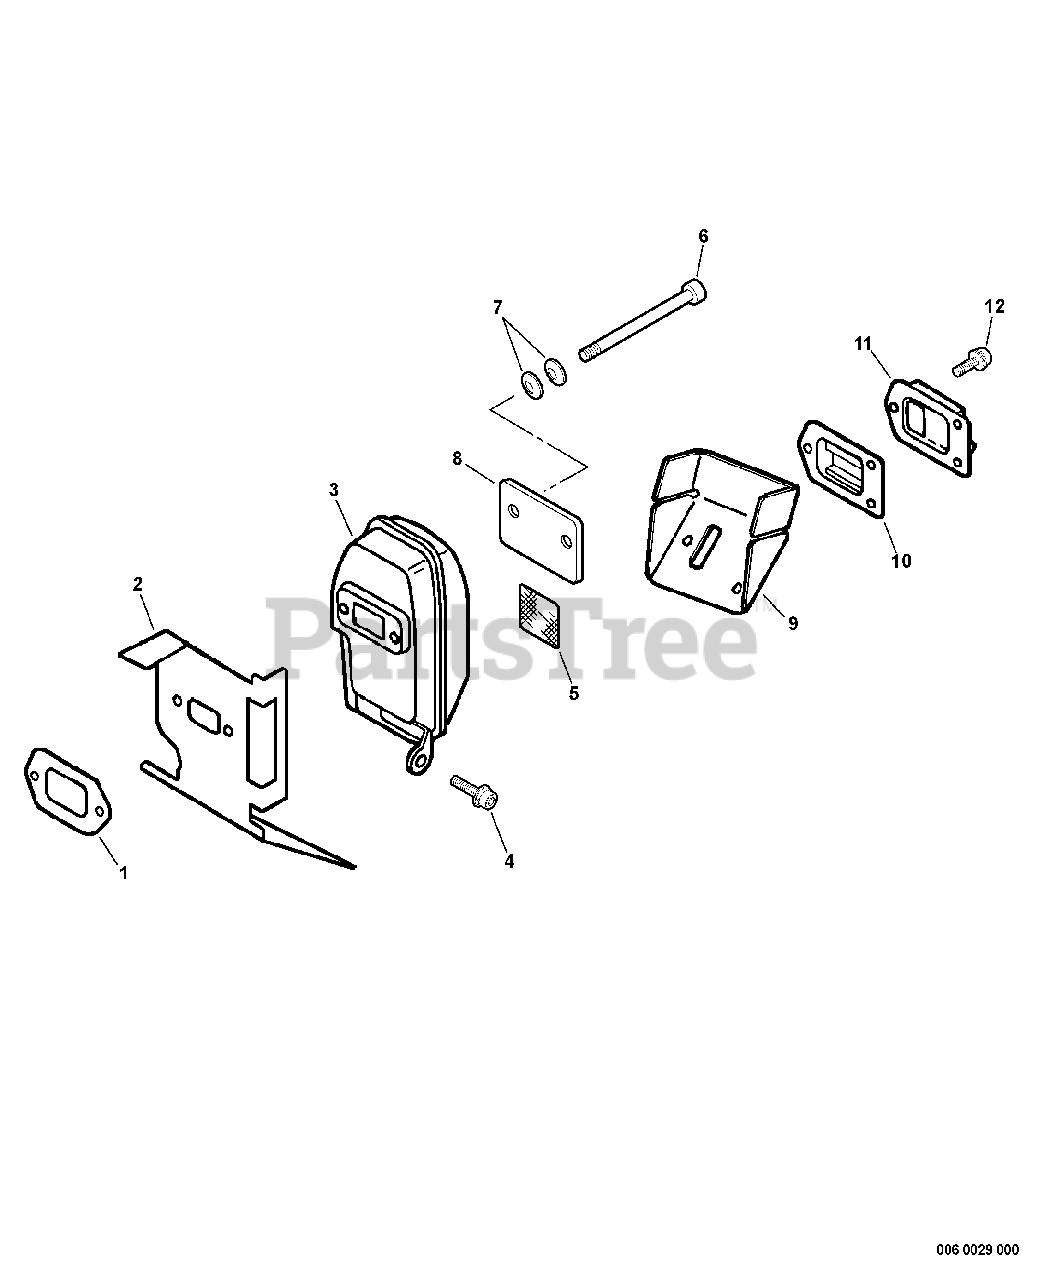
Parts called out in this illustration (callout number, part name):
1	GASKET, EXHAUST
2	SHIELD, EXHAUST
3	MUFFLER
4	SCREW - 5X16
5	SCREEN, SPARK ARRESTOR
6	BOLT - 5X65
7	WASHER - CONICAL
9	GASKET, EXHAUST
10	GUIDE, EXHAUST - INNER
11	GUIDE, EXHAUST
12	SCREW - 4X12
